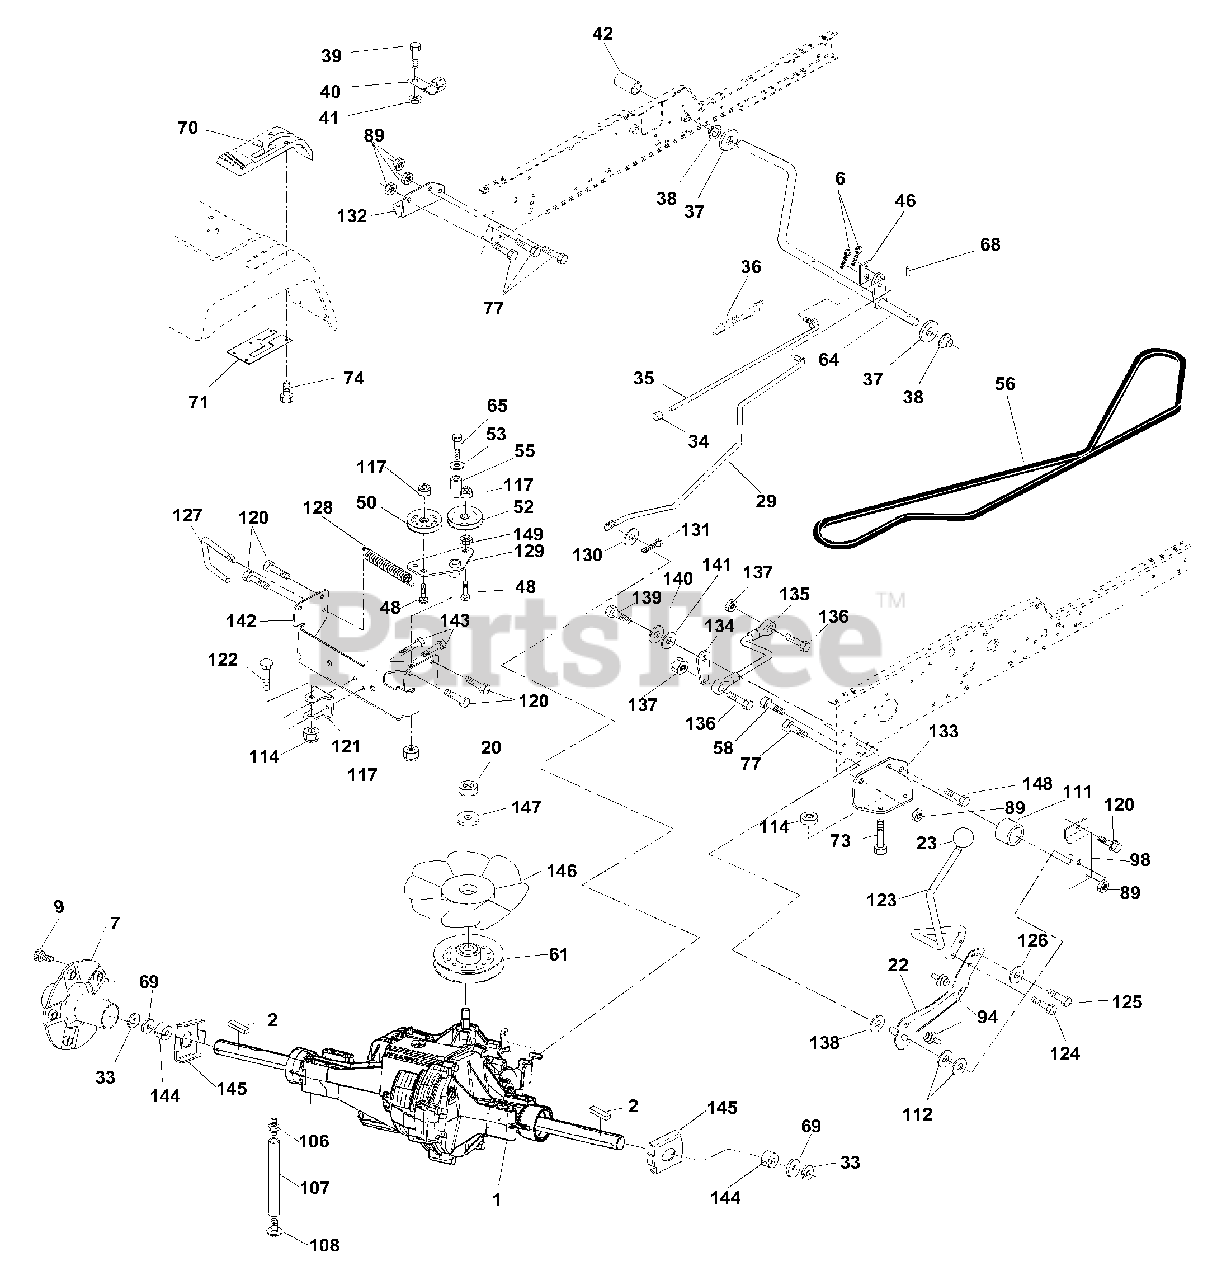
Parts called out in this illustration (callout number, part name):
2	Key Sq. 1/4 x 1/4 x 2
5	Nut, Crownlock 3/8-16
6	Pin, Cotter
7	Wheel, Hub Assembly
22	Lever Asm Shift
29	Brake, Rod
34	Cap, Parking Brake
35	Rod, Parking Brake
36	Spring, Drive Ground
37	Washer 25/32 x 1-1/4 x 16 Ga.
39	Screw, Fin. #10-24 x 1
40	Actuator, Interlock Switch
41	Nut Centerlock 10-24 Unc
42	Cover, Pedal
46	Retainer, Spring
50	Pulley, Idler, Flat
52	Pulley, Idler, Grooved
53	Washer,Hardened
55	Bearing, Idler
58	Bolt Fin Hex 7/16-14 x 1-1/2
61	Pulley, Transaxle
64	Shaft, Brake Pedal
65	Bolt, Shoulder
70	Console Automatic YT/GT
71	Plate Console Shift
72	Nut, Crownlock 5/16-18
73	Bolt Hex Flghd 5/16-18 x 3 Gr5
74	Screw Hex Wsh. Hi-Lo 1/4-1/2
77	Bolt Fin Hex 7/16-14 x 1
89	Nut Crownlock 7/16-14 Unc
94	Fastener Christmas Tree
98	Bracket Shift
104	Bracket Idler Stationary
106	O-Ring Asm Hydro Gear
107	Line Fuel Hydro 15" VGT
108	Cap Asm Vent Hydro Gear
111	Spacer Shift Lever VGTH
112	Washer Nylon High Temp
114	Nut Lock Hex W/Ins 5/16-18 Unc
117	Nut, Lock Flg. 3/8-16
120	Screw 3/8-16 x .75
121	Bracket Strap Torque
122	Bolt RDHDSQ 5/16-18 Unc x 2-1/2
124	Bolt Shoulder 5/16-18 x .561
125	Screw 5/16-18 x 5/8
126	Washer SRRTD 5/16 ID x 1.0 x .125
127	Link Control Clutch
128	Spring Drive GRND
129	Bracket Asm Idler Tensioning
130	Washer 13/32 x 5/8 x 16 Ga.
131	Pin Cotter 3/32 x 1/2
132	Bracket Mtg Hydro 3500 LH VGT
133	Bracket Mtg Hydro 3500 RH VGT
134	Arm Shift Hydro 3500
135	Link Asm Control Hydro 3500
136	Bolt Fin Hex 5/16-18 Unc x 1.00
137	Nut Lock 5/16-18 NC Thd.
138	Washer Thrust 5/8 x 1.10 x 1/32
139	Bolt 1/4-28 Unf Gr8 w/Patch
140	Washer Lock Hvy. Helical 1/4
141	Washer 9/32 x 3/4 x 10 Ga.
142	Strap Torque HG-3500
143	Screw Thdrol 5/16-18 x 1/2
144	Washer Spacer Axle HG-3000
145	Washer Axle Flange HG-3000
146	Fan 7" Hydro
148	Screw 3/8-16 x 1.0
149	Washer 13/32 x 7/8 x 10 Ga.
